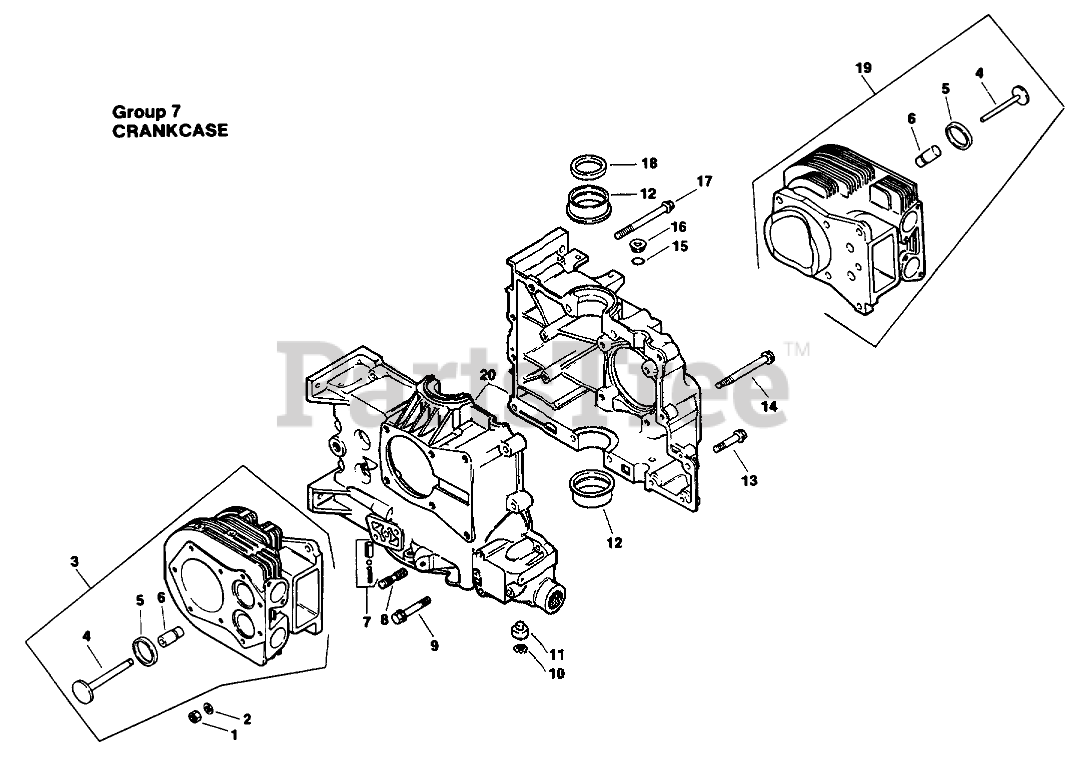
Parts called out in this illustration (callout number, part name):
1	Nut
2	Washer-Flat
3	Kit-#2 Cylinder Barrel (Incl. Ref. #4-6)
4	Valve-Exhaust
5	Inset-Valve Seat
6	Guide-Valve
7	Kit-Oil Relief
8	Stud-Step
9	Screw-Hex. Flange
10	Ring-Retaining
11	Shaft-Governor
12	Bearing-Sleeve (Std.)
13	Screw-Hex. Flange
14	Screw-Hex. Flange
15	O-Ring
16	Plug
17	Screw-Hex Flange
18	SeaI-RearOil
19	Kit-#2 Cylinder Barrel (Incl. Ref. #4-6)
